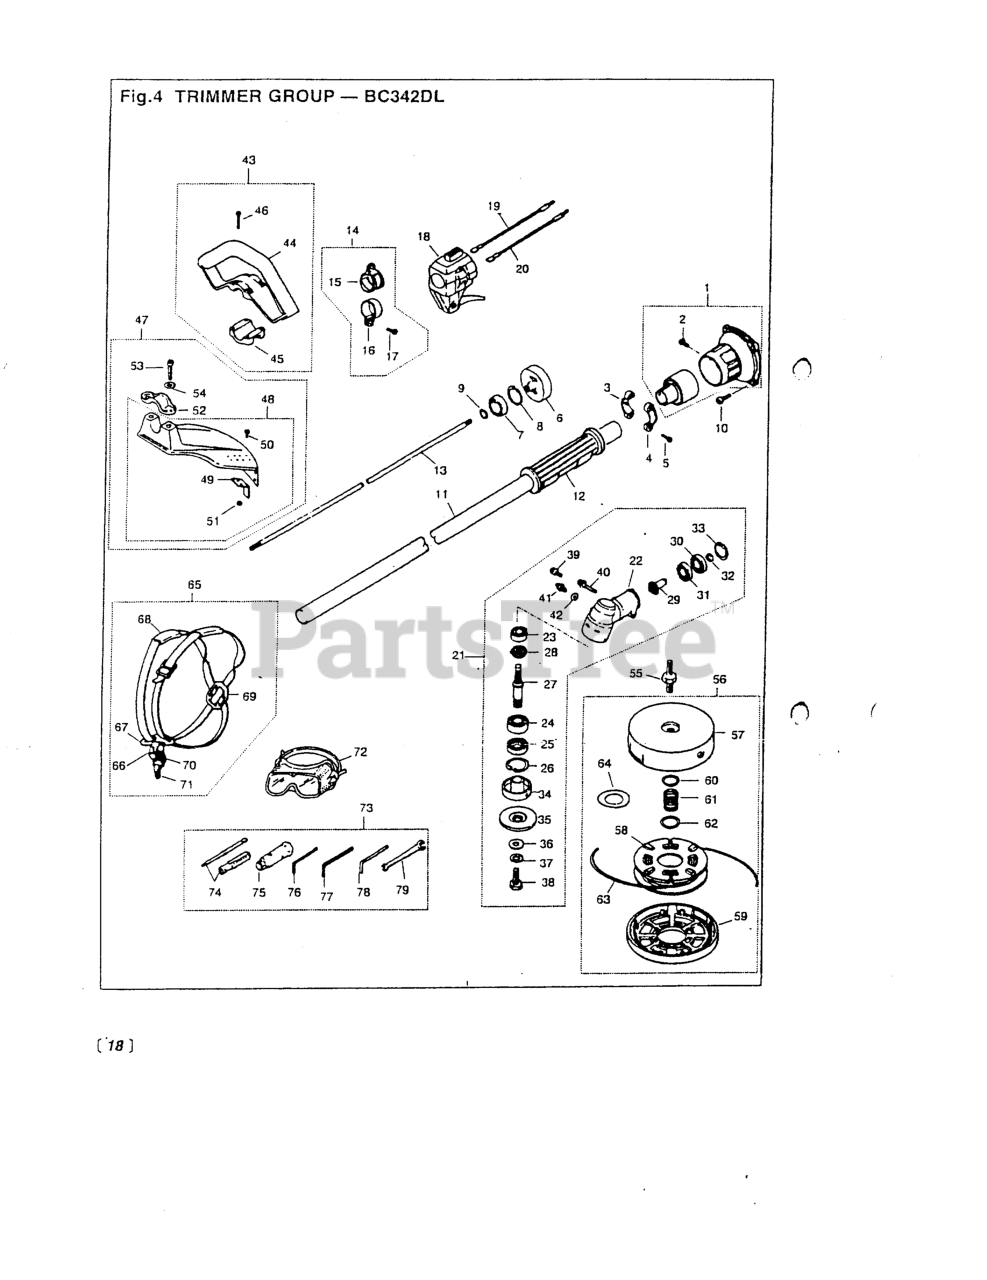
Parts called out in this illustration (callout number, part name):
1	HOUSING ASSY (RPLS-11100)
2	SCREW, M6 x 10
3	CLAMP, RIGHT (RPLS -11130)
4	CLAMP, LEFT (RPLS-11140)
5	BOLT
6	DRUM, CLUTCH
7	BEARING
8	RING, SNAP, M35 X 1.5
9	RING, SNAP, M15 X 1.0
10	BOLT, M6 X 20
13	SHAFT, SPLINE
14	HANGER ASSY. (NLA)
15	HANGER
16	CLAMP
17	SCREW, M5 x 25
19	CORD-A, BLACK
20	CORD-B, RED
21	GEARCASE (RPLS-13005)
22	GEARCASE (RPLS -13113)
23	BEARING (RPLS T3403-13510)
25	SEAL, OIL
26	RING, SNAP, M32 x 1.2
27	SHAFT, GEAR
28	GEAR, BEVEL
31	BEARING (RPLS T3403-13510)
32	RING, SNAP
34	HOLDER (A)
35	HOLDER (B)
36	WASHER, M8 x 2.3 (RPLS -20823)
37	WASHER (RPLS 3180-13270)
38	BOLT, LH
39	BOLT, M5 X 10
40	BOLT, M6 x 1.35
41	FITTING, GREASE
42	WASHER, M6 X .8
43	HANDLE ASSEMBLY
44	HANDLE
45	CLAMP
46	SCREW, M5 x 35
47	GUARD ASSY (RPLS -24001)
48	GUARD COMP.
49	BLADE
50	SCREW, M5 x 12
51	NUT
52	CLAMP
53	BOLT, M6 x 1.30
54	WASHER, M6 X 15
55	ARBOR, 8MM
56	6
59	COVER
60	PLATE, LARGE
62	PLATE, SMALL
63	CORD
64	SPACER
68	PROTECTOR
73	TOOL SET
74	SCREWDRIVER
76	WRENCH (TOOL)
77	WRENCH (TOOL)
78	BAR
79	SPANNER, 8 X 10 (RPLS 2540- )
